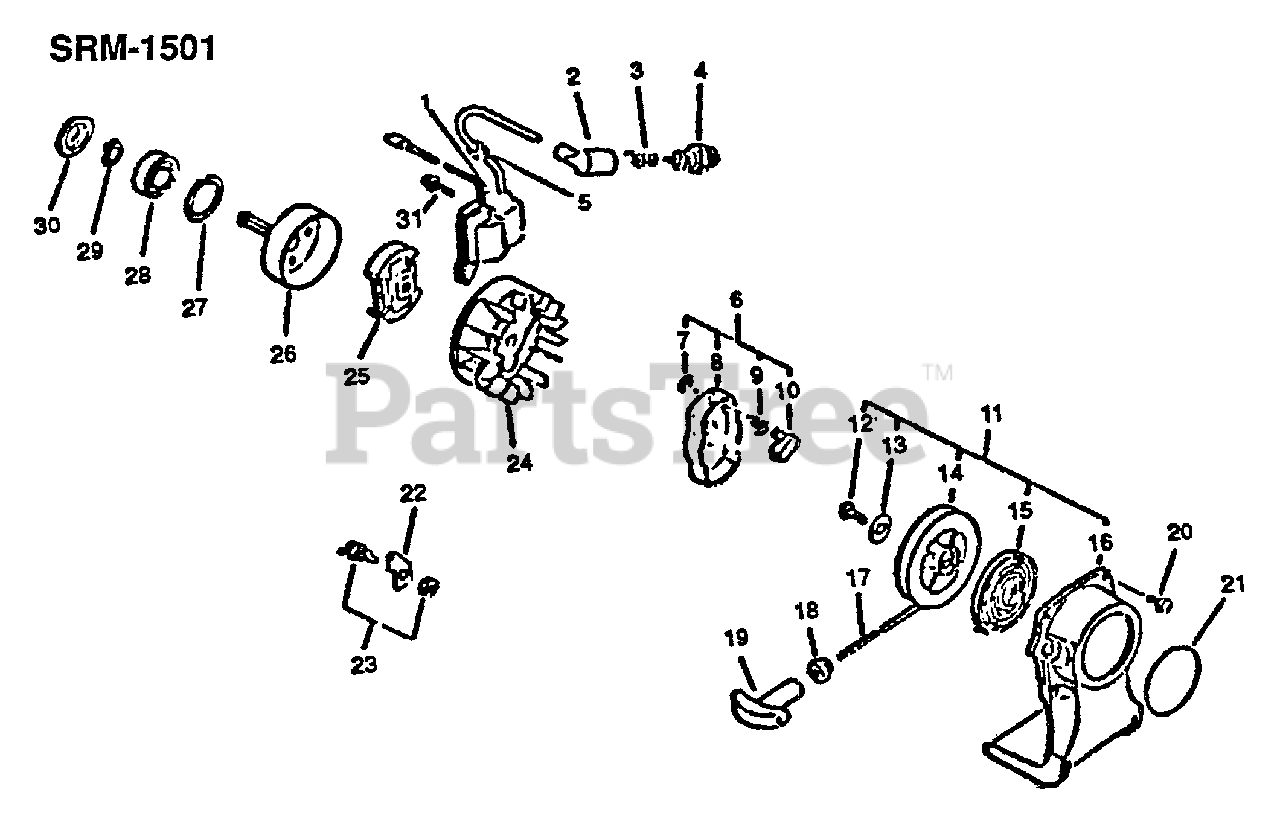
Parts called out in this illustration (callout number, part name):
1	Coil, Ignition
2	Cap, Spark Plug
2	Drum, Clutch
3	Coil, Spark Plug Cap
4	Plug, Spark (BPM-7A)
5	Bushing
6	Pawl Asy, Starter
7	E-Ring 4
8	Catcher, Pawl
9	Spring, Return
10	Pawl, Starter
11	Starter Asy
13	Washer
14	Drum, Starter
15	Spring, Rewind
16	Case, Stater (BL)
17	Rope, Starter
18	Guide, Rope
19	Grip, Starter
20	Screw 4X16
21	Label, Echo
22	Bracket, Switch
23	Switch, Ignition
24	Flywheel
25	Clutch Asy
27	Circlip 32
28	Bearing, Ball 6001
29	Circlip 12
31	Screw 4X22
